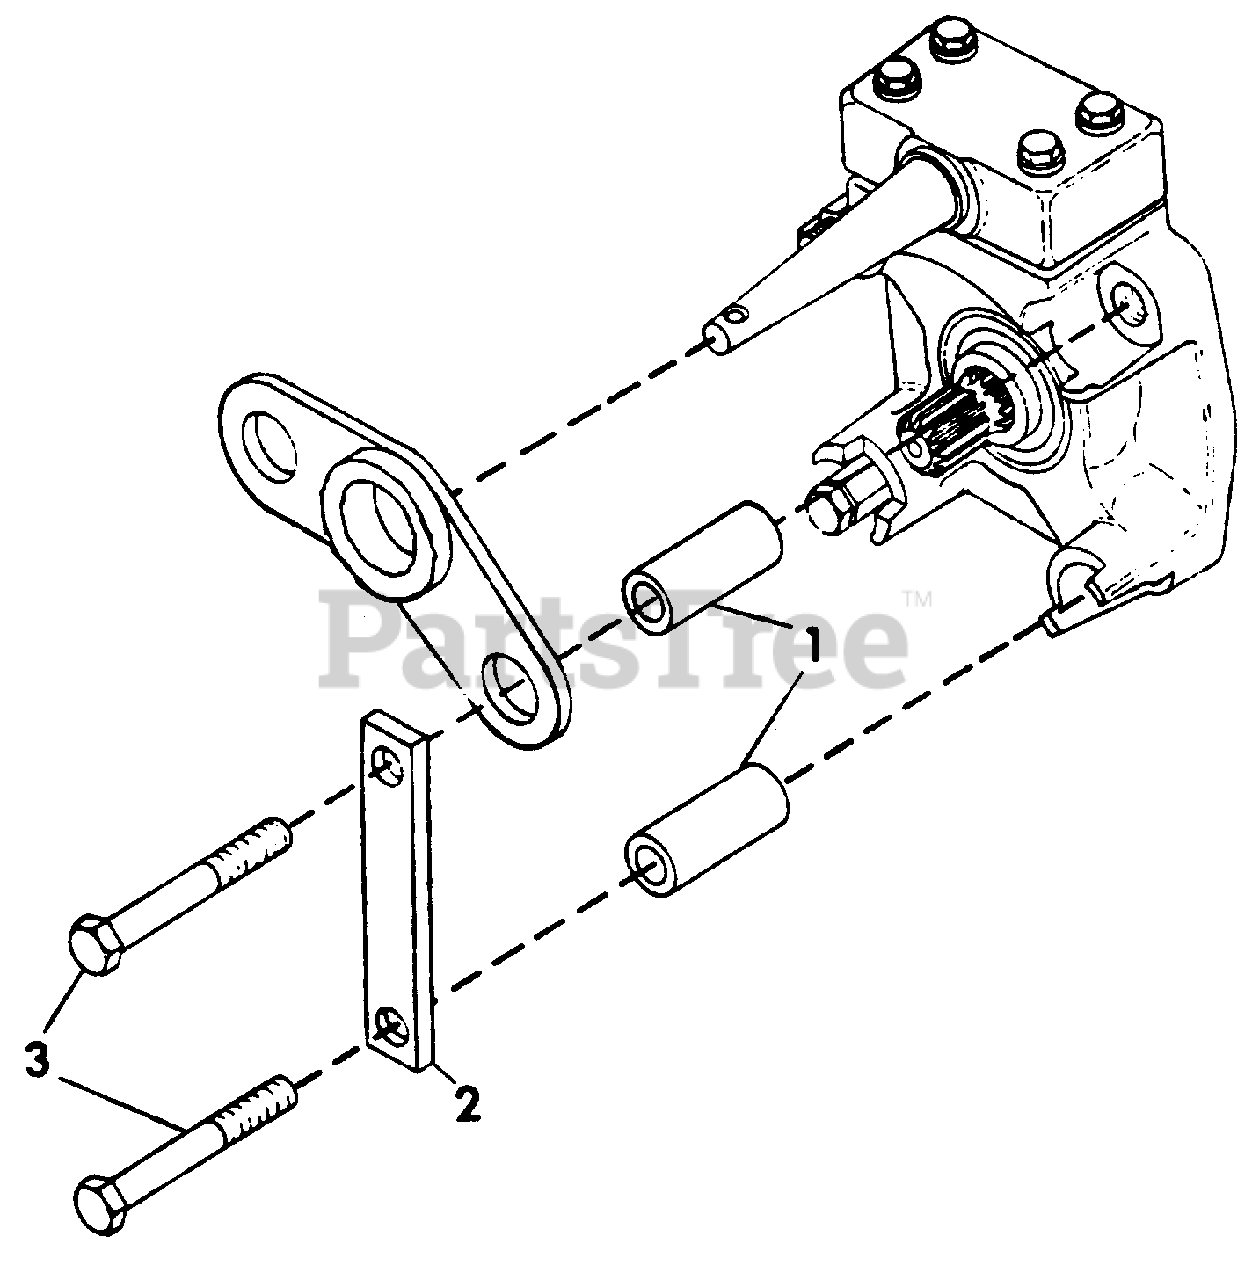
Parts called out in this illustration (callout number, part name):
1	SPACER
2	STRAP, LOCKING
3	BOLT, HEX - 1/2 - 13 X 4-1/2
